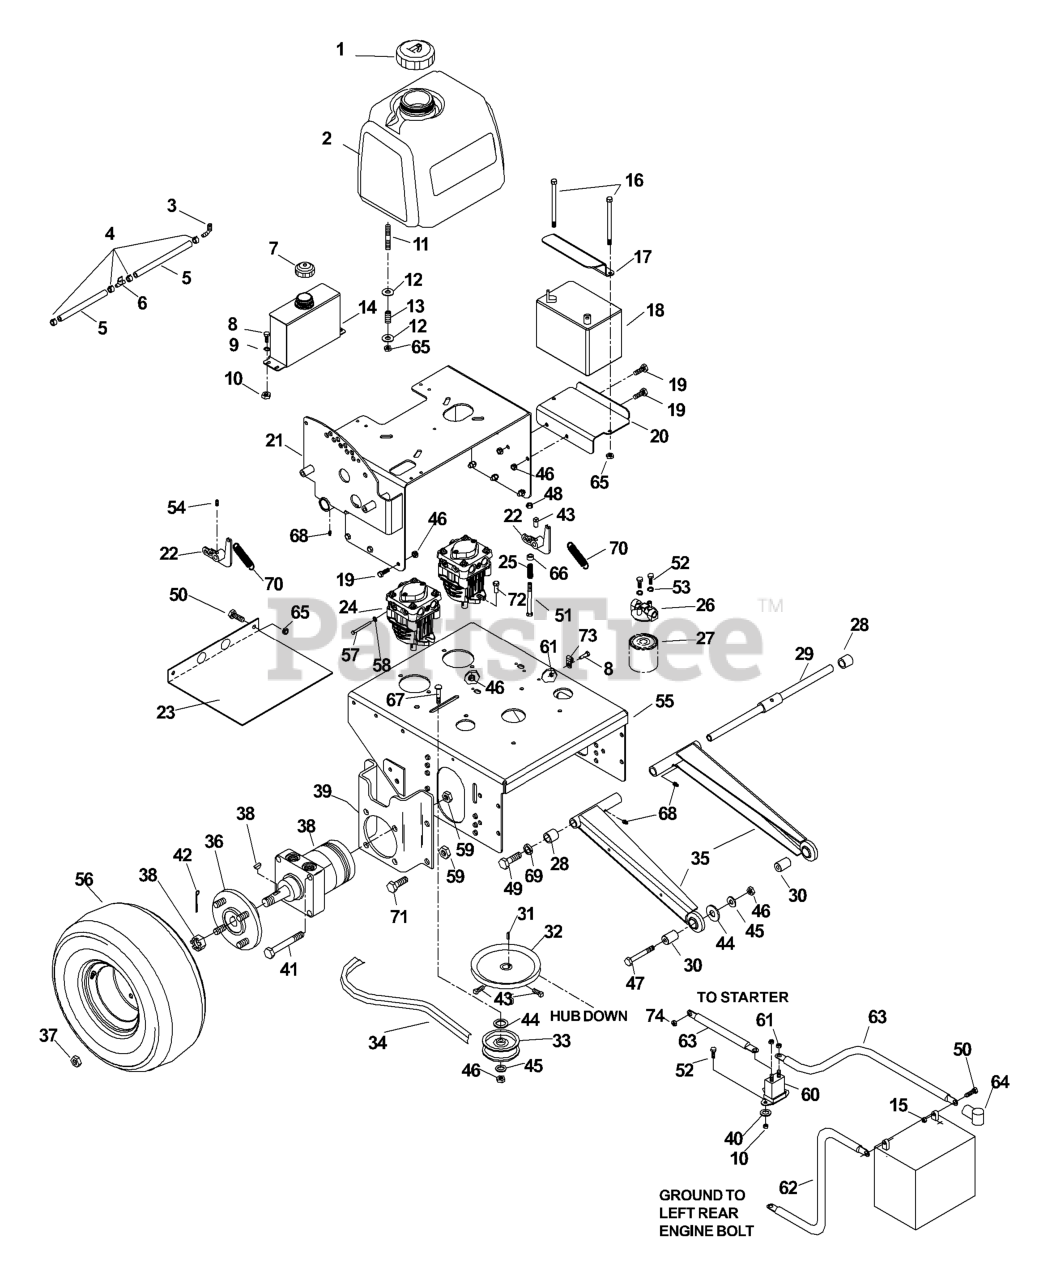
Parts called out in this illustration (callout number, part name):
1	FUEL CAP ANTI-SPLASH
3	HOSE BARB 90 DEGREE
4	HOSE CLAMP
5	GAS LINE 10"
6	FUEL VALVE
7	HYDRAULIC CAP
8	HCS 1/4C X 3/4 HCS
9	WASHER 1/4 FLAT
10	NUT 1/4C CENTER LOCK
11	STUD, 5/16C
12	WASHER 5/16 FLAT
14	OIL TANK BLK
15	NUT 5/16C CENTERLOCK
16	BOLT - 5/16 X 7
17	BATTERY STRAP
18	BATTERY, 12 V 330 AMP
19	SCREW 3/8C X 3/4 HEX CAP
20	BATTERY TRAY
21	TANK SUPPORT
22	PUMP ARM WELDMENT
23	LOWER BELT SHIELD
24	HG_PUMP
26	FILTER HEAD
27	HYDRAULIC OIL FILTER
29	STRUT SHAFT
30	FRONT SPACER
31	KEY 5 MM SQ X 25 MM
33	IDLER PULLEY
34	TRANSMISSION BELT
35	STRUT WELDMENT
36	HUB.WHEEL.ZTR
37	LUG NUT 1/2F
38	WHEEL MOTOR
38	SEAL KIT - GEN I
39	MOTOR MOUNT
40	WASHER 1/4 INT TOOTH
41	HCS 1/2C X 2 3/4
42	COTTER PIN
43	SCREW 5/16C X 5/8 SQ HEAD
44	WASHER 1/2 FLAT
45	WASHER 3/8 FLAT
46	NUT 3/8C CENTERBLOCK
47	HCS 3/8C X 2 1/4
48	NUT 3/8-16 NYLOC
49	HHCS 1/2-13 X 1
50	HCS 5/16C X 3/4
51	HEX SCREW 3/8-20 X 2.75
52	HCS 1/4C X 5/8
53	LOCKWASHER 1/4"
54	5/16C X 5/8 "V" POINT
55	REAR DECK ORANGE PAINTED
56	TIRE/WHEEL ASSY
56	TIRE.TURF.SAVER.18X7.5-8
56	VALVE STEM TR-412
56	WHEEL
57	CLEVIS PIN
58	NUT PUSH
59	NUT 1/2-13 HEX NYLOC ZD
61	NUT.1/4-20.HEX.NYLOC.ZD
62	CABLE-NEGATIVE
63	CABLE POSITIVE, LONG
65	NUT 5/16 NYLOC
67	RHSNB 3/8C X 2
68	ZERK
69	WASHER 1/2" SPLIT LOCK
70	SPRING-TRANS
71	HCS 1/2C X 1 1/4 SERRATED HEAD
72	4CS 3/8C X 1 SERRATED HEAD
73	DOUBLE TUBE CLAMP
74	JAM NUT 1/4C (2 2 PW01)
